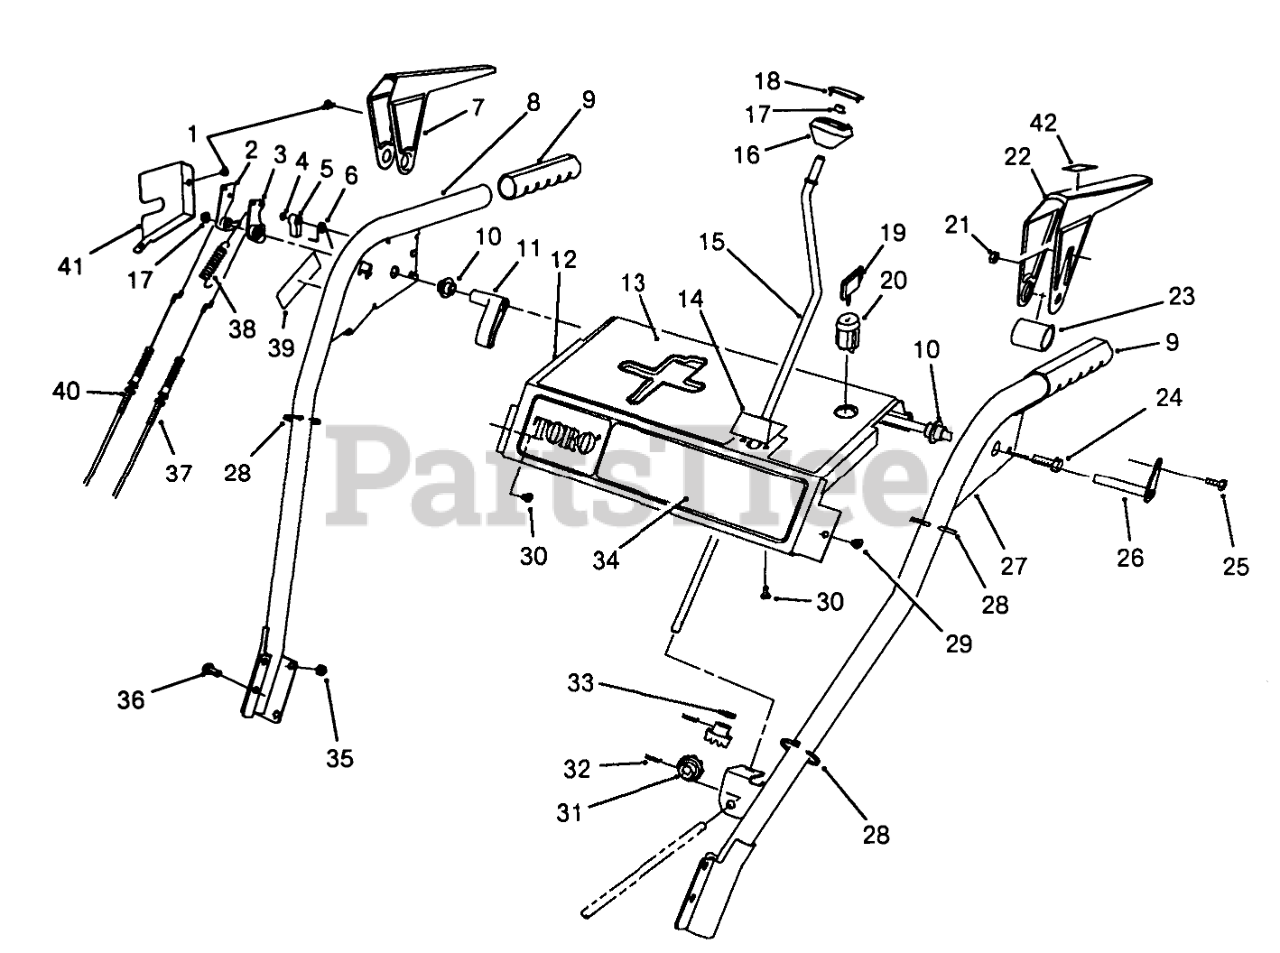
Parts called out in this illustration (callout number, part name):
1	SCREW-HH
2	TANG-LOCKING
3	CAM-RELEASE
4	E-RING-RETAINER
5	LATCH-LOCKING
6	SPRING-TORSION
7	Lever-Impeller
8	Handle-R.H.
9	HANDLE GRIP
10	BUSHING-LEVER
11	LEVER-TRIP
12	Panel-Control
13	Decal-Panel, Top
14	PLATE-GUIDE
15	CRANK-ROD, CHUTE
16	KNOB-CONTROL, CHUTE
17	RETAINER-PUSH ON
18	COVER-KNOB
19	KEY-IGNITION
20	SWITCH
21	NUT-LOCK, NI
22	Lever-Traction
23	SPACER-LEVER, TRACTION
24	SCREW-HHF
25	SCREW-HWH
26	CROSS ROD ASM
27	LH HANDLE WA 28"-32"B
28	TIE-CABLE
29	SCREW-HWHTF
30	SCREW-PPH
31	GEAR-UNIVERSAL
32	PIN-SPRING
33	WASHER-RUBBER
34	DECAL-FRONT PANEL (828)
35	NUT-LOCK, NI
36	SCREW-HHF
37	CABLE-TRACTION
38	Spring-Extension
39	Decal-Warning
40	CABLE-IMPELLER
41	Cover Lever Lock
42	DECAL-LEVER
